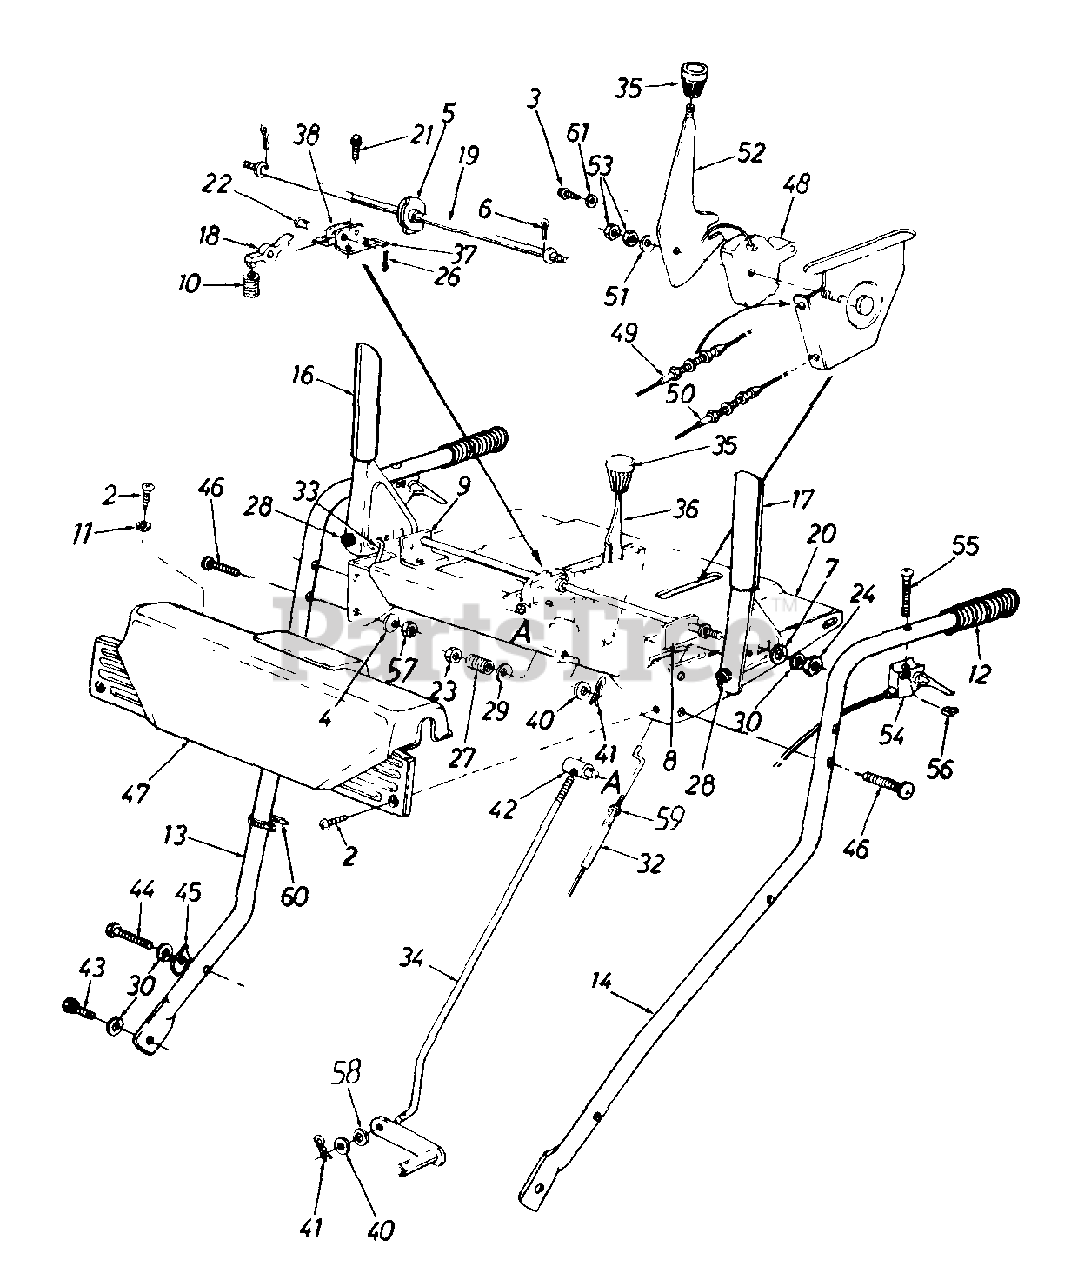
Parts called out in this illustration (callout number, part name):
2	Truss Mach. B-Tap Scr. #10 x .5
3	Hex AB-Tap Scr. 1/4 x .62" Lg.
4	Bell-Wash .325" I.D. x .88" O.D.
5	Cam Handle Lock
6	Cotter Pin 3/32" Dia. x .75" Lg.
7	Washer (Special) .72" O.D.
10	Compression Spring
11	Fl-Wash .188" I.D. x .43" O.D.
13	Handle - R.H.
14	Handle - L.H.
16	Engagement Handle - R.H.
17	Engagement Handle - L.H.
18	Pawl Handle Lock
19	Rod Cam
22	Clevis Pin .437" Dia. x .65" Lg.
23	Hex Ins. L-Nut 3/8-24 Thd.
24	Hex Nut 5/16-18 Thd.
26	Cotter Pin 3/32" Dia. x 1" Lg.
27	Compression Spring
28	Rubber Bumper
29	Bell-Wash .38" I.D. x .88" O.D.
30	L-Wash. 5/16" I.D."
32	Auger Clutch Cable
33	Drive Clutch Cable
34	Shift Rod
35	Shift Knob
36	Shift Handle
40	Fl-Wash .344" I.D. x .62" O.D.
41	Internal Cotter Pin 5/16" Dia.
42	Ferrule
43	Hex Bolt 5/16-18 x .62" Lg.
44	Hex Bolt 5/16-18 x 1.75" Lg. (Gr. 5)
45	Handle Tab
46	Curved Carr. Bolt 5/16-18 x 1.5" Lg.
47	Handle Panel
48	Cable Guide
49	Chute Control Cable
50	Chute Control Cable w/Clip
51	Bell-Wash .325" I.D. x .93" O.Q.
53	Hex Cent. L-Nut 5/16-18 Thd.
54	Track Steer Cable w/Trigger
55	Oval C-Sunk Hd. Scr. 10-24 x 1.375" Lg.
56	Flat Weld Nut #10-24 Thd.
57	Hex Nut 5/16-18 Thd.
58	Spr. Wash .32" I.D. x .62" O.D.
59	Hex Nut #10-24 Thd.
60	Cable Tie
